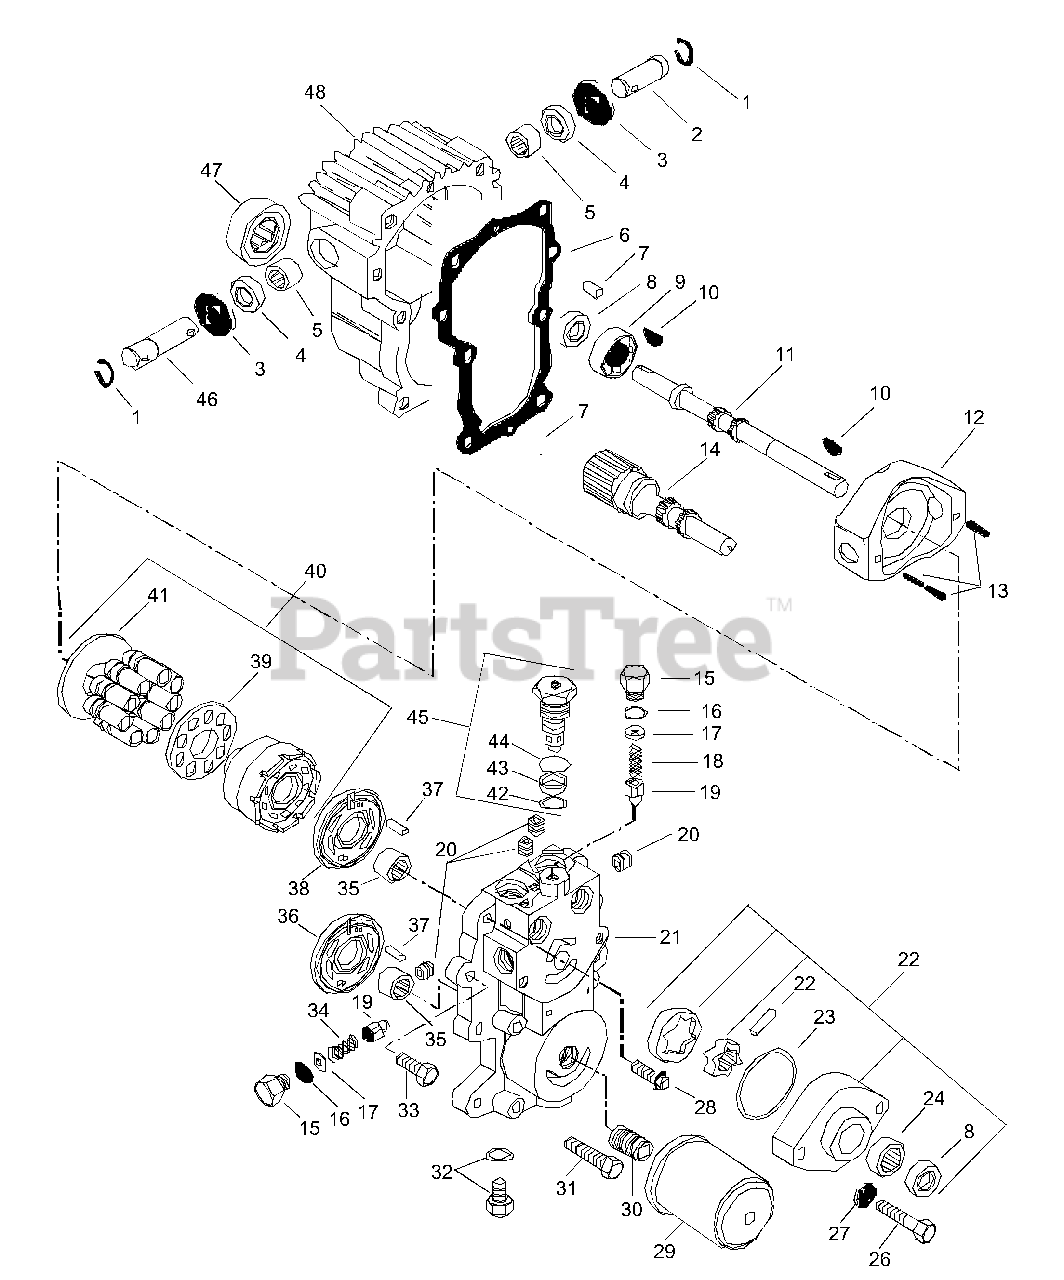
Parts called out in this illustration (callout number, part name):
1	Ring-Retaining-External .688 x .042
2	Trunnion Shaft
3	Washer-Flat-Steel .699 x 1.375 x .059
4	Seal .625 x 1.187 x .187
5	Bearing-Needle .688 x .876 x .63
6	Gasket
7	Dowel Pin
8	Seal .625 x 1.128 x .250
9	Bearing-Ball 1.0 x 2.0 x .50
10	Key-Woodruff .188 x .75
11	Pump Shaft
12	Swashplate Variable
13	Pin-Roll .188 x .63
14	Motor Shaft
15	Plug-Hex Head
16	O-Ring .414 x .562 x .072
17	Shim Package
18	Spring-Compression
19	Relief Valve Cone
20	Pipe Plug
21	Center Section
22	Pin
23	O-Ring 2.364 x 2.504 x .072
24	Bearing-Needle .625 x .875 x .50
25	Charge Pump Assembly
26	Bolt-Hex .44-14 x 2.00 Grade 5
27	Washer-Flat-Steel .469 x .719 x .108
28	Screw-12 Point .38-16 x 1.25 Grade 5
29	Oil Filter
30	Union
31	Bolt-Hex .38-16 x 2.00 Grade 5
32	Threaded Plug
33	Bolt-Hex .38-16 x 1.50 Grade 5
34	Spring-Compression
35	Bearing-Needle 17MM x .938 x .62
36	Motor Valve Plate
37	Dowel Pin
38	Valve Plate
39	Slipper Retainer
40	Cylinder Block Kit
41	Thrust Plate
42	O-Ring .614 x .750 x .070
43	O-Ring .614 x .750 x .046
44	O-Ring .770 x .968 x .097
45	Check Valve Assembly
46	Trunnion Shaft
47	Bearing-Roller 1.27 x 2.05 x 15MM
48	Housing w/Seals and Bearings
